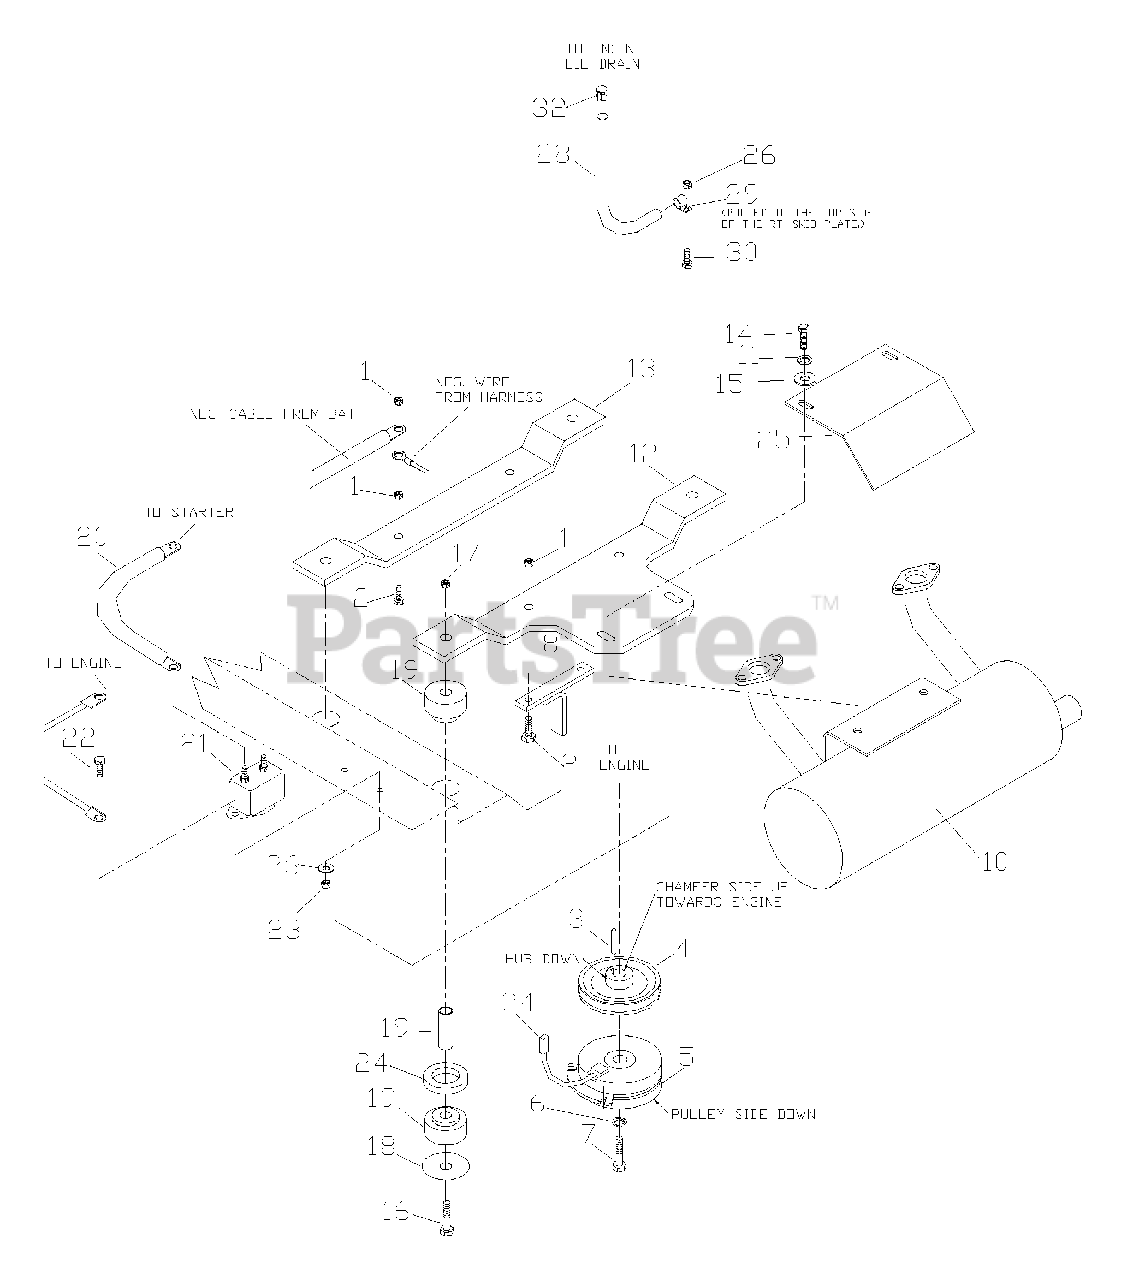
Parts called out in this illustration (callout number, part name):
1	NUT 5/16 LOCK
2	HCS 5/16 X 1.75
3	KEY 1/4 SQ.
6	WASHER 7/16 LOCK
7	HCS 7/16F X 2.5
8	CLUTCH TIE DOWN
9	KAWASAKI PIGTAIL
11	WASHER 5/16 LOCK
12	ENGINE MOUNT
13	ENGINE MOUNT
14	HCS 5/16 X .750
15	WASHER 5/16 FLAT
16	HCS 1/2 X 3.25
17	NUT 1/2 NYLOC
20	CABLE, POSITIVE
22	HCS 1/4 X .625
23	NUT 1/4 CTR. LOCK
25	MUFFLER GUARD
26	WASHER 1/4 INT. TOOTH
27	GROUND WIRE
28	OIL DRAIN HOSE
30	HCS 1/4 X .750
31	CHOKE CONTROL
34	CLUTCH PIGTAIL
